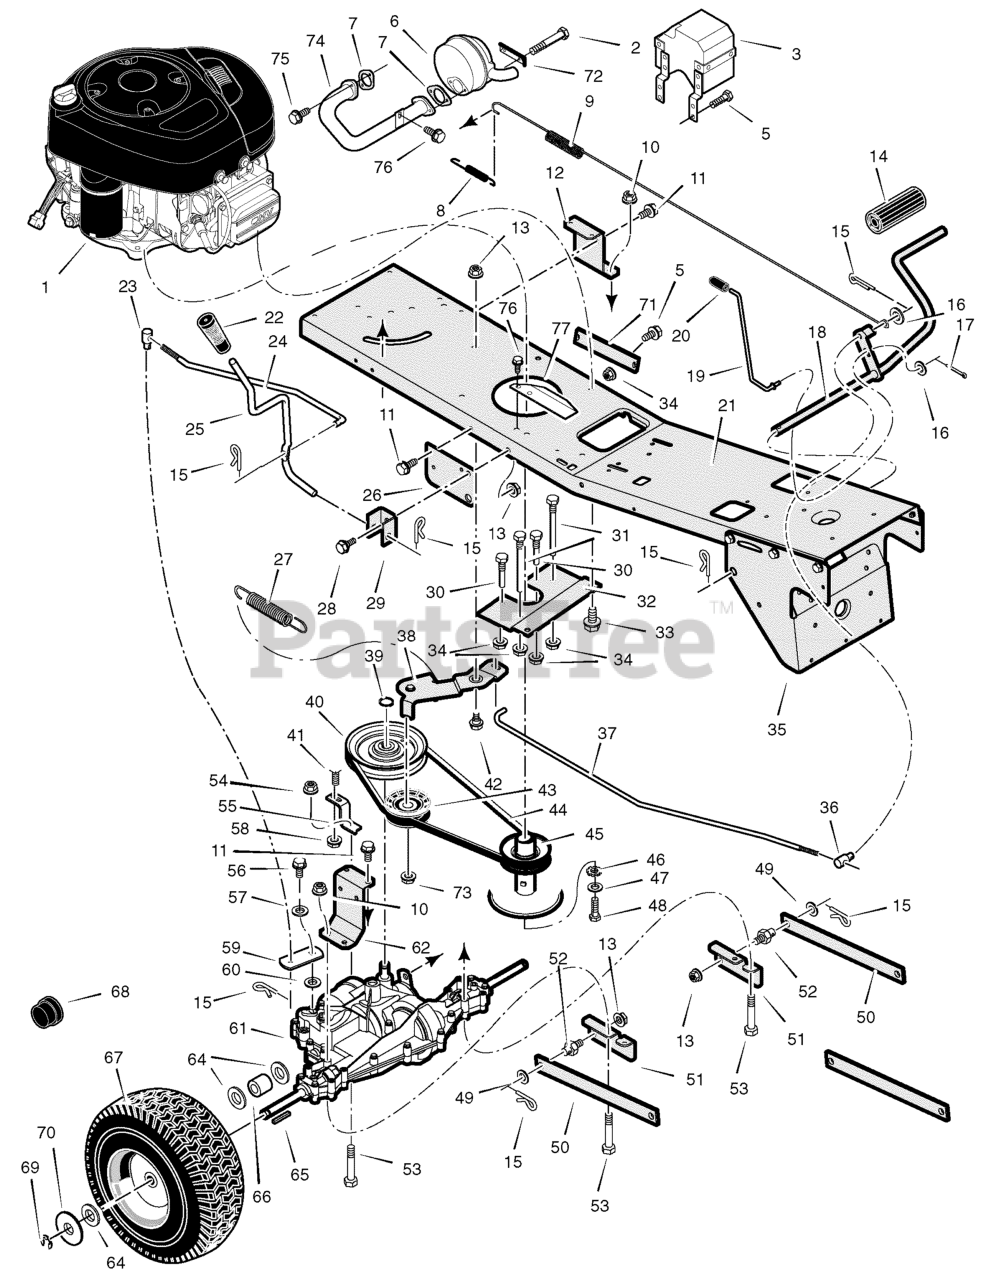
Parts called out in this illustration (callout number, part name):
1	Engine, Briggs & Stratton
2	Bolt, Hex
3	Shield Assembly, Heat
5	Screw
6	Muffler
7	Gasket, Muffler
8	Spring, Extension
9	Spring, Extension
10	Nut
11	Screw
12	Bracket, Left Transaxle
13	Nut, Flange
14	Cover, Pedal
15	Pin, Cotter
16	Washer
17	Pin, Cotter
18	Pedal Assembly
19	Rod, Parking Brake
20	Grip, Parking Brake Rod
22	Grip, Shift Lever
23	Nut, Adjusting
24	Link, Shift
25	Lever, Shift
26	Bracket, Lift Pivot
27	Spring, Extension
28	Bolt, Shoulder
29	Bracket, Pivot
30	Guide, Belt -Short
31	Guide, Belt -Long
32	Plate, Belt Guide
33	Bolt
34	Nut, Flange
35	Bracket, Support
36	Nut, Adjusting
37	Rod, Clutch
38	Clutch Arm Assembly
39	Ring, Retainer
40	Pulley, Drive
41	Bolt, Carriage
42	Bolt, Shoulder
43	Pulley, Idler
44	Belt, Motion Drive
45	Pulley, Split Stack
46	Washer, Star
47	Washer
48	Bolt, Hex
49	Washer
50	Arm, Rear
51	Bracket, Rear Hanger
52	Pin, Threaded Shoulder
53	Bolt, Hex
54	Nut
55	Bracket, Torque Reactor
56	Screw
57	Washer, Shift Yoke
59	Yoke, Shift
60	Washer
61	Transaxle, Peerless **
62	Bracket, Right Transaxle
64	Washer
65	Key, Square
66	SPACER, Rear Wheel
67	Wheel, Rear -15" *
68	Cap, Hub
69	E-Ring
70	Washer
71	Plate, Reinforcement
72	Lock, Screw
73	Nut
74	Tube, Exhaust
75	Screw
76	Screw
77	Shield, Heat
